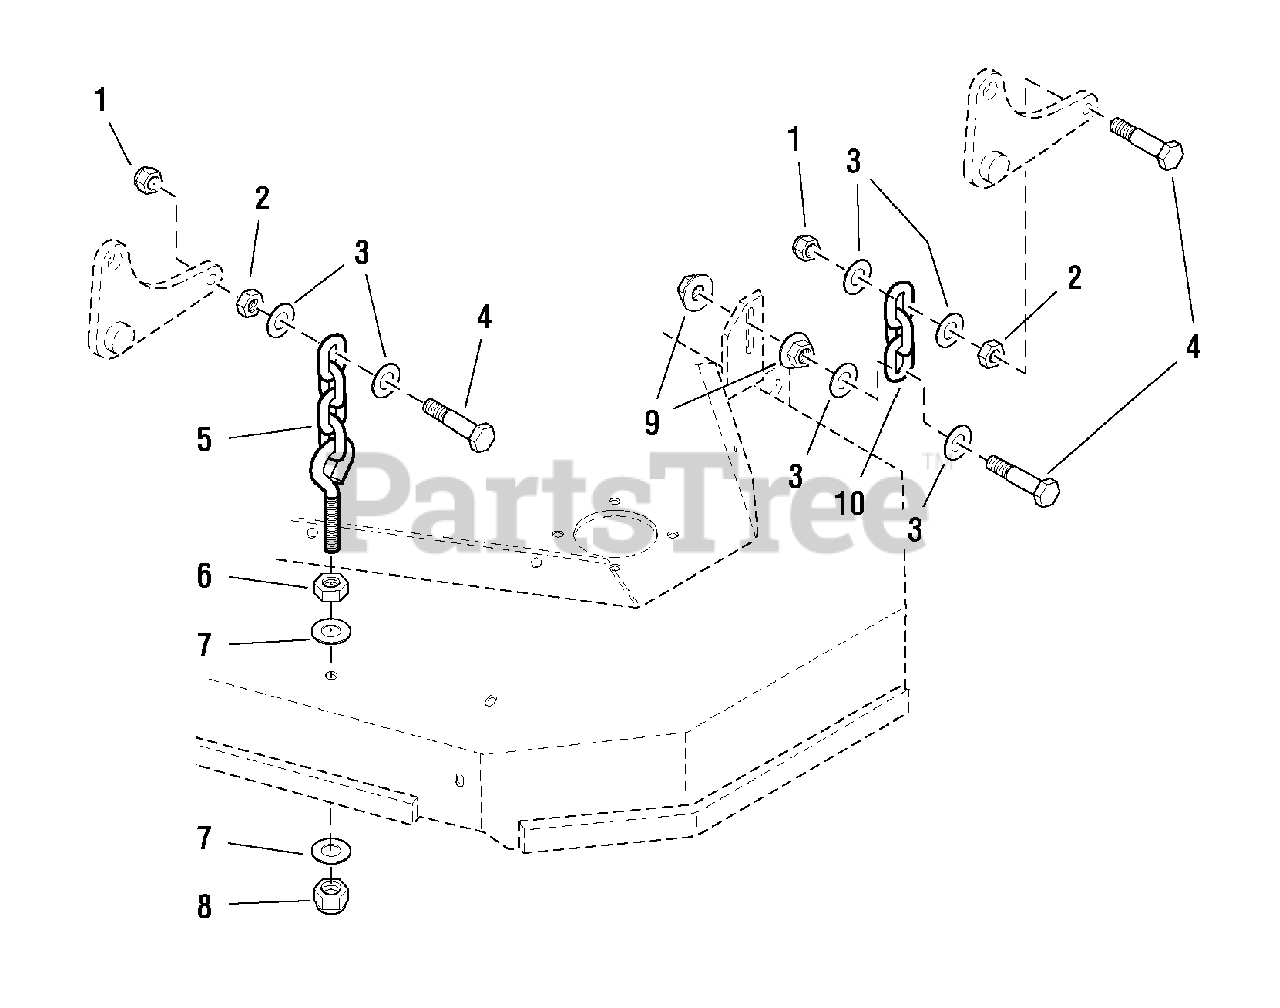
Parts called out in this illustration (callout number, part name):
1	NUT, 3/8-16 Hex Nylon Lock
2	NUT, 3/8-16 Hex Jam
3	WASHER, 3/8" SAE
4	BOLT, 3/8-16 x 1-3/4
5	HANGER, FRONT DECK - 4 LINK, 5.5" EB
6	NUT, 1/2-13 Hex
7	WASHER, 1/2" SAE
8	NUT, 1/2-13 Hex Nylon Lock
9	NUT, 3/8-16 Hex Serrated Flange
10	CHAIN, 3 LINKS
